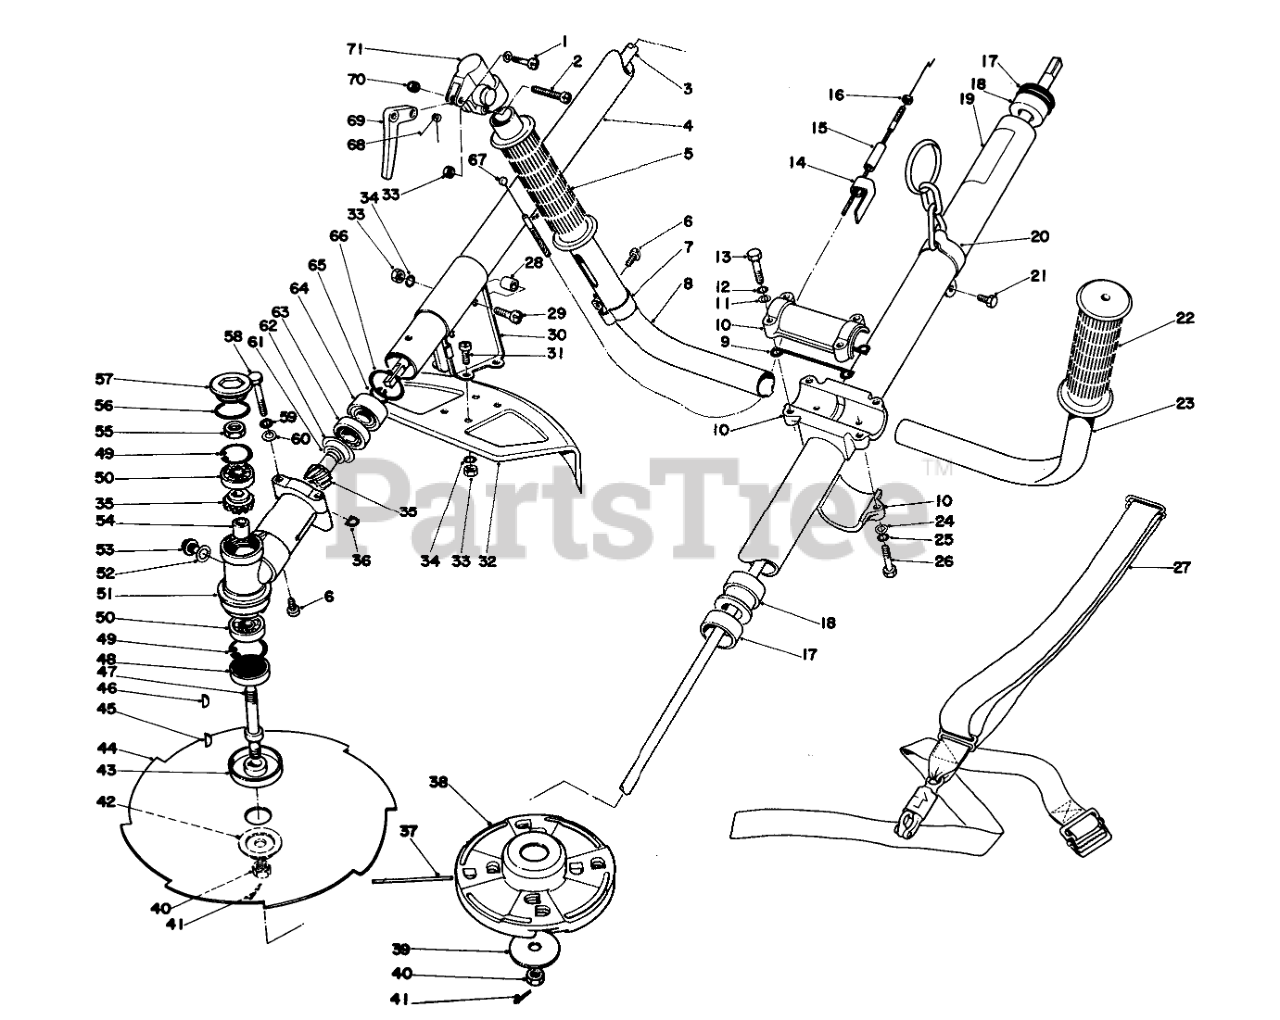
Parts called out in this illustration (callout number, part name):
1	Screw
2	Screw
3	Shaft-Driving
4	Housing, Driving Shaft (Incl. Ref. #17 & 18)
5	Right Hand Grip
6	SCREW
8	Handle
9	Spacer
10	Bracket, Handle (Incl. Ref. #9-13 & 24-26)
11	WASHER
12	Washer
14	Clamp
17	Bushing
19	Decal Warning
20	Swivel Hook
21	Screw
22	LH GRIP
23	Handle
24	Washer
25	Washer
27	Shoulder Strap Deluxe
28	Spacer
29	Screw
30	Bracket-Head Guard
31	SCREW
32	Shield
33	Nut
34	Washer
35	Gear Set
36	Spacer
37	Cotter Pin
38	Cutter Head
39	WASHER
41	Split Pin
42	Adapter-Blade
43	Plate-Blade Fixing
44	Weed Blade
45	Woodruff Key
46	Woodruff Key
47	Shaft, Power Take Off
48	Oil Seal
49	Circlip
50	Ball Bearing
51	Housing Gear
52	Gasket
54	Spacer
56	O-Ring
57	Lid, Gear Housing
59	Washer
60	WASHER
61	Washer
62	Washer
63	Ball Bearing
64	Ball Bearing
65	Circlip
66	Circlip
67	Throttle Cable
68	Return Spring
69	THROTTLE LEVER
71	Bracket Throttle Trigger
